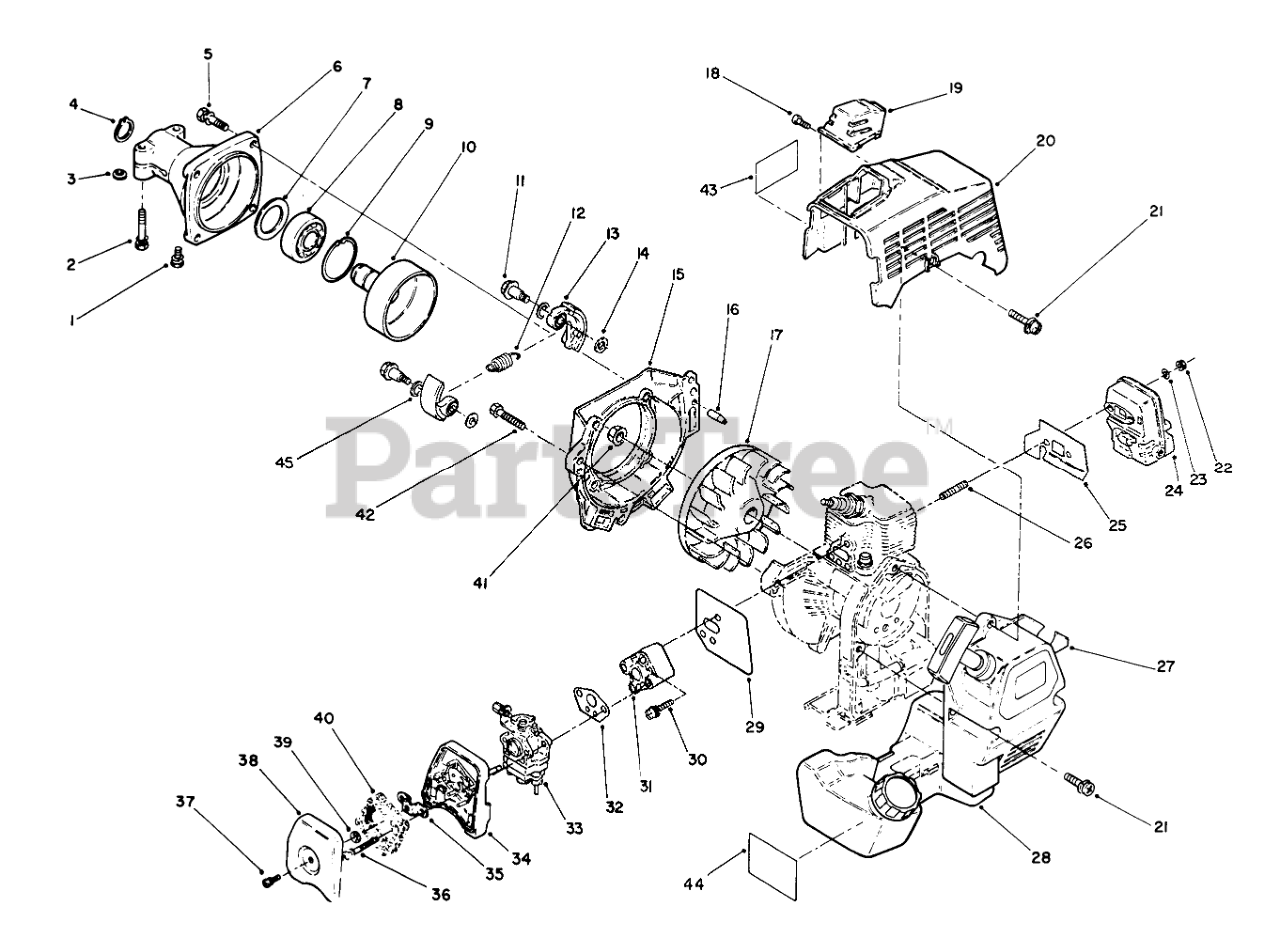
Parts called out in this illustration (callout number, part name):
1	Screw/Washer
2	BOLT-WASHER/ENG
3	WASHER
4	SNAP RING
5	Bolt/Washer
6	CLUTCH CASE
7	Washer
8	BALL BEARING
9	SNAP RING
10	CLUTCH DRUM
11	CLUTCH BOLT
12	Spring
13	SHOE, CLUTCH
14	WASHER
15	Case-Fan
17	Fan
18	SCREW & WASHER
19	SPARK PLUG GUARD
20	TOP COVER
21	SCREW & WASHER
22	MUFFLER FLANGE NUT
23	GASKET
24	MUFFLER ASSEMBLY
25	MUFFLER GASKET
26	MUFFLER STUD
27	RECOIL ASSEMBLY
28	Tank Assembly-Fuel
29	INSULATOR GASKET
30	SCREW & WASHER
31	INSULATOR
32	CARBURETOR GASKET
33	Carburator Assembly
34	CLEANER CASE
35	BRACKET
36	SCREW W/ WASHER
37	SCREW & WASHERE
38	CLEANER COVER
40	CLEANER ELEMENT
42	BOLT AND WASHER
43	DECAL-SURFACE, HOT
44	DECAL - FUEL TANK
45	SPRING WASHER
